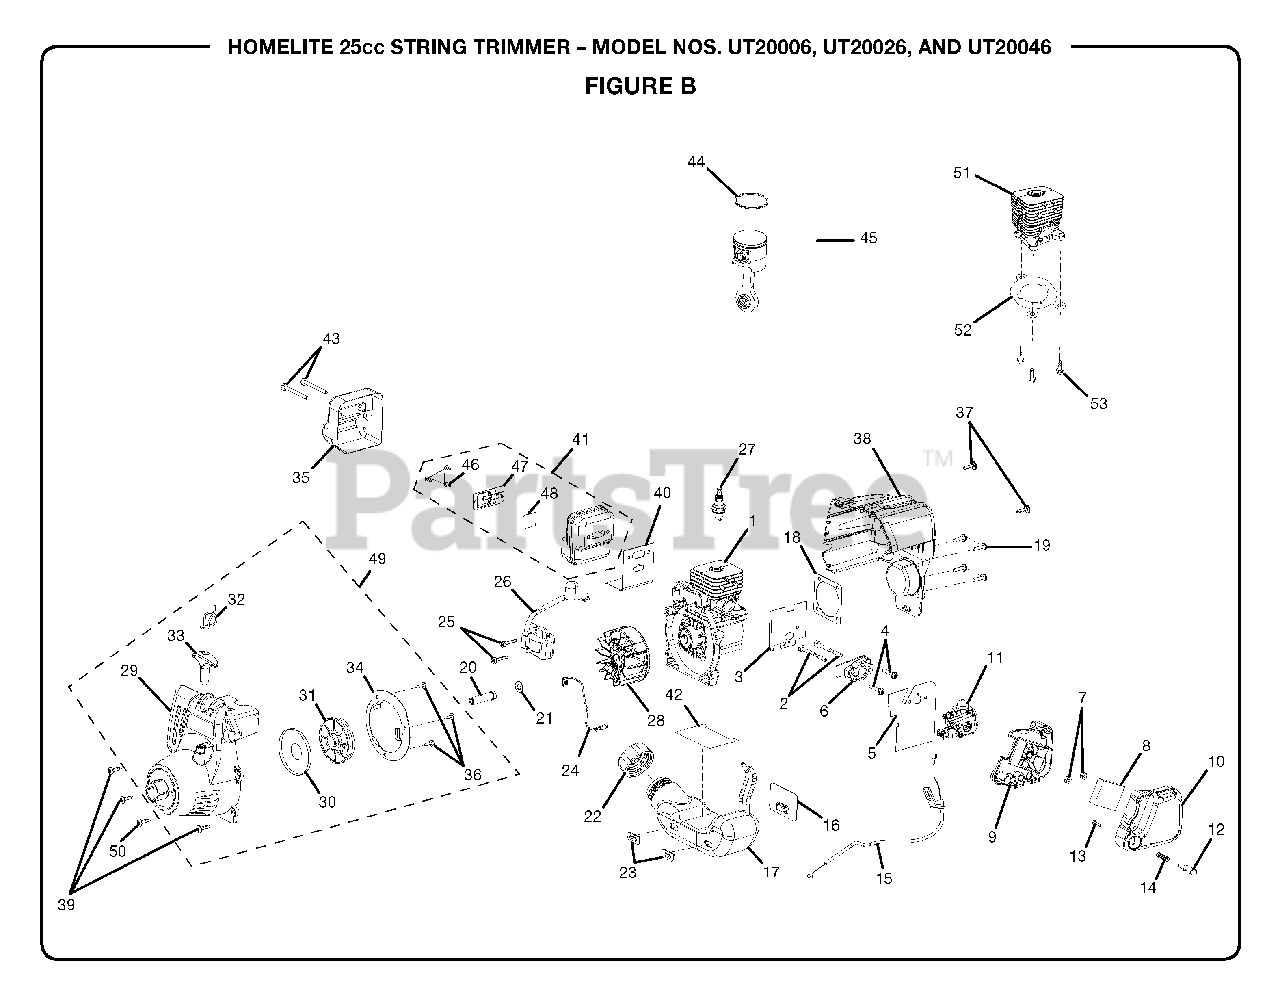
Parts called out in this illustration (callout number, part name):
1	SHORT BLOCK ASSEMBLY
2	CARBURETOR BOLTS
3	INTAKE GASKET
4	SCREW (10-24 X 1-1/16 in. PAN HD.)
5	CARBURETOR GASKET
7	LOCK NUT (10-24)
8	AIR FILTER
9	AIR FILTER BOX
10	AIR BOX COVER
11	CABURETOR ASSEMBLY
12	BUTTON SWITCH
13	SCREW, (6-19 X 1/2 in. T.F.)
14	COMPRESSION SPRING
15	THROTTLE CABLE W/HANGER
17	FUEL TANK
18	CRANK CASE COVER GASKET
19	SCREW (10-24 X 3/4 in. PAN HD. TORX W/LW)
20	DRIVE CONNECTOR
21	FLAT WASHER
22	FUEL CAP ASSEMBLY
23	BUMPER
24	LEAD W/TERMINALS
25	SCREW (8-32 X 1 in. THREAD FORMING)
26	IGNITION MODULE
27	SPARK PLUG (CHAMPION RCJ4)
28	ROTOR AND PAWL ASSEMBLY
29	STARTER HOUSING ASSEMBLY
30	SPRING AND CONTAINER
31	STARTER PULLEY
32	STARTER ROPE
33	STARTER GRIP
34	BAFFLE
35	HEAT SHIELD
36	SCREW (8-16 X 1/2 in. THREAD FORMING)
37	SCREW (10-14 X 3/4 in. THREAD FORMING)
38	REAR HOUSING
39	SCREW (10-24 X 3/4 in. TRUSS HD.)
40	MUFFLER GASKET
41	CATALYTIC MUFFLER ASSEMBLY
43	SCREW (10-24 X 2-3/16 in. TORX HD. )
44	PISTON RING
45	PISTON ASSEMBLY
46	SCREW (6-20 X 1/4 in. PAN HD.)
47	OUTLET TUBE
48	SCREEN
49	COMPLETE STARTER ASSEMBLY
50	SCREW (10-24 X 7/8 in. TORX HD.)
52	CYLINDER GASKET
53	SCREW (M5 X 20 mm)
